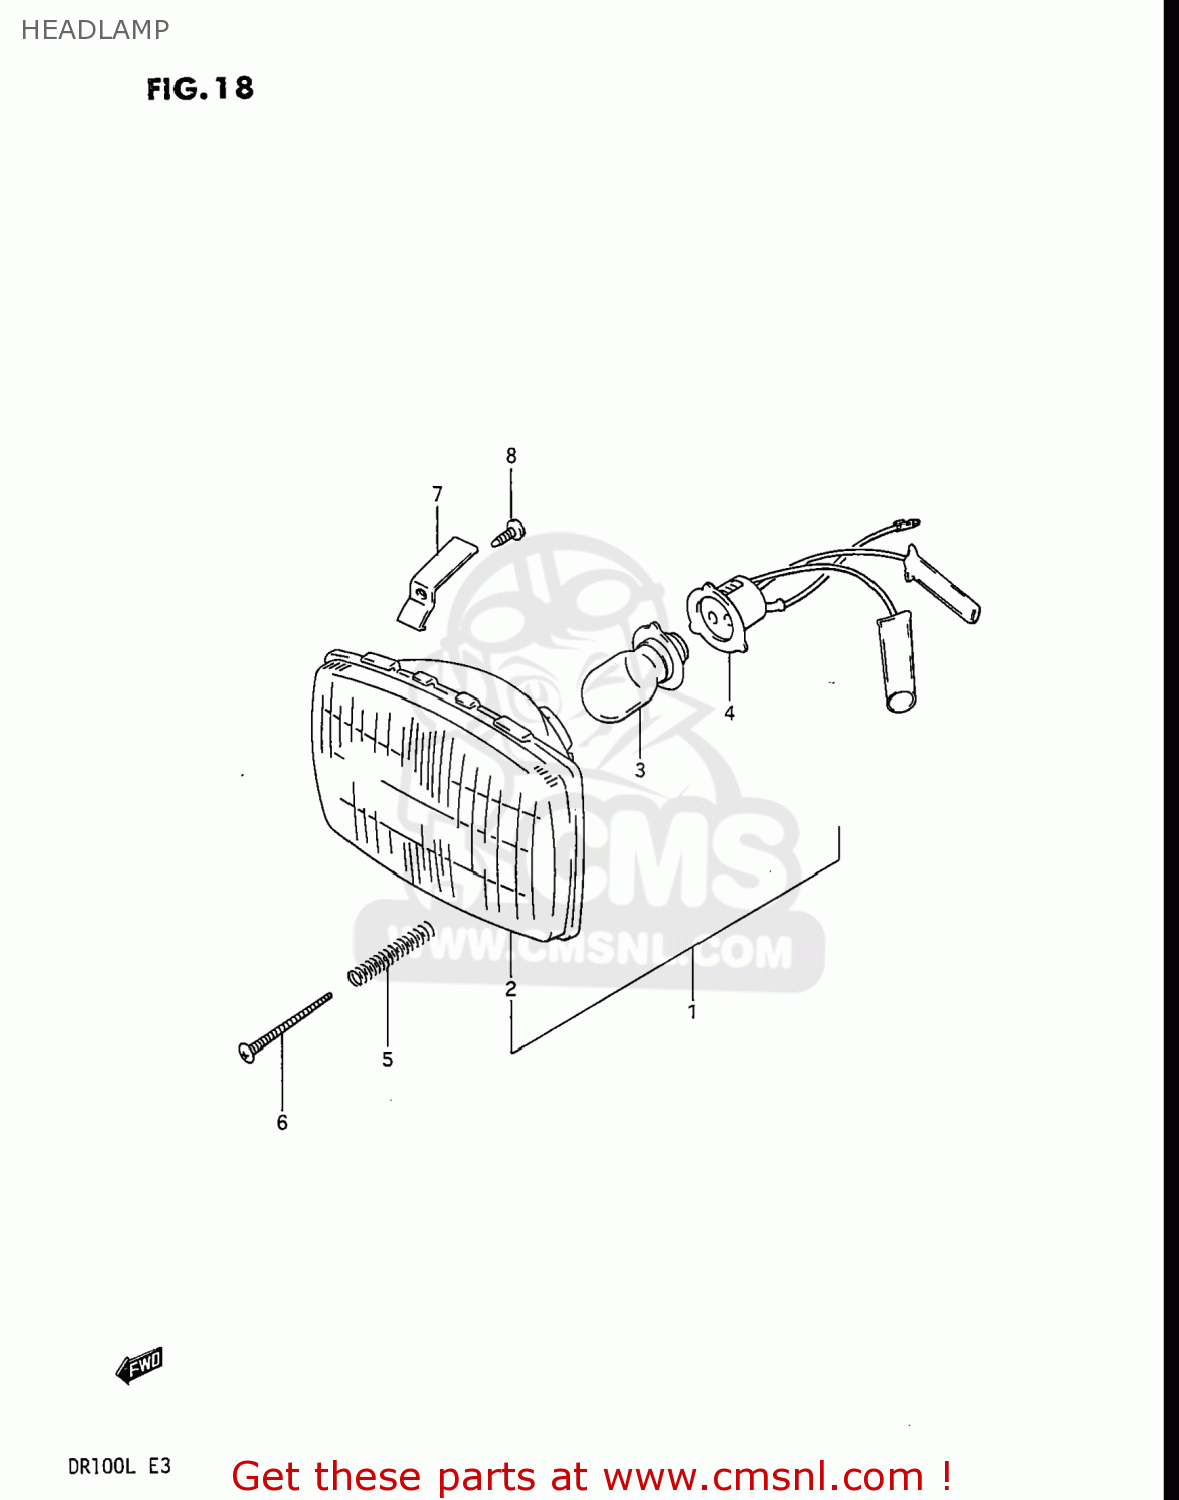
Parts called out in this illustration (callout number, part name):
1	HEADLAMP ASSEMBLY
2	LAMP UNIT
3	BULB(6V15/15W/STANLEY,A3598HA)
4	SOCKET,HEADLAMP
5	SPRING,HEAD LAMP ADJUSTER
6	SCREW,HEADLAMP ADJUST
7	SPRING
8	SPRING,HEADLAMP ADJUST
